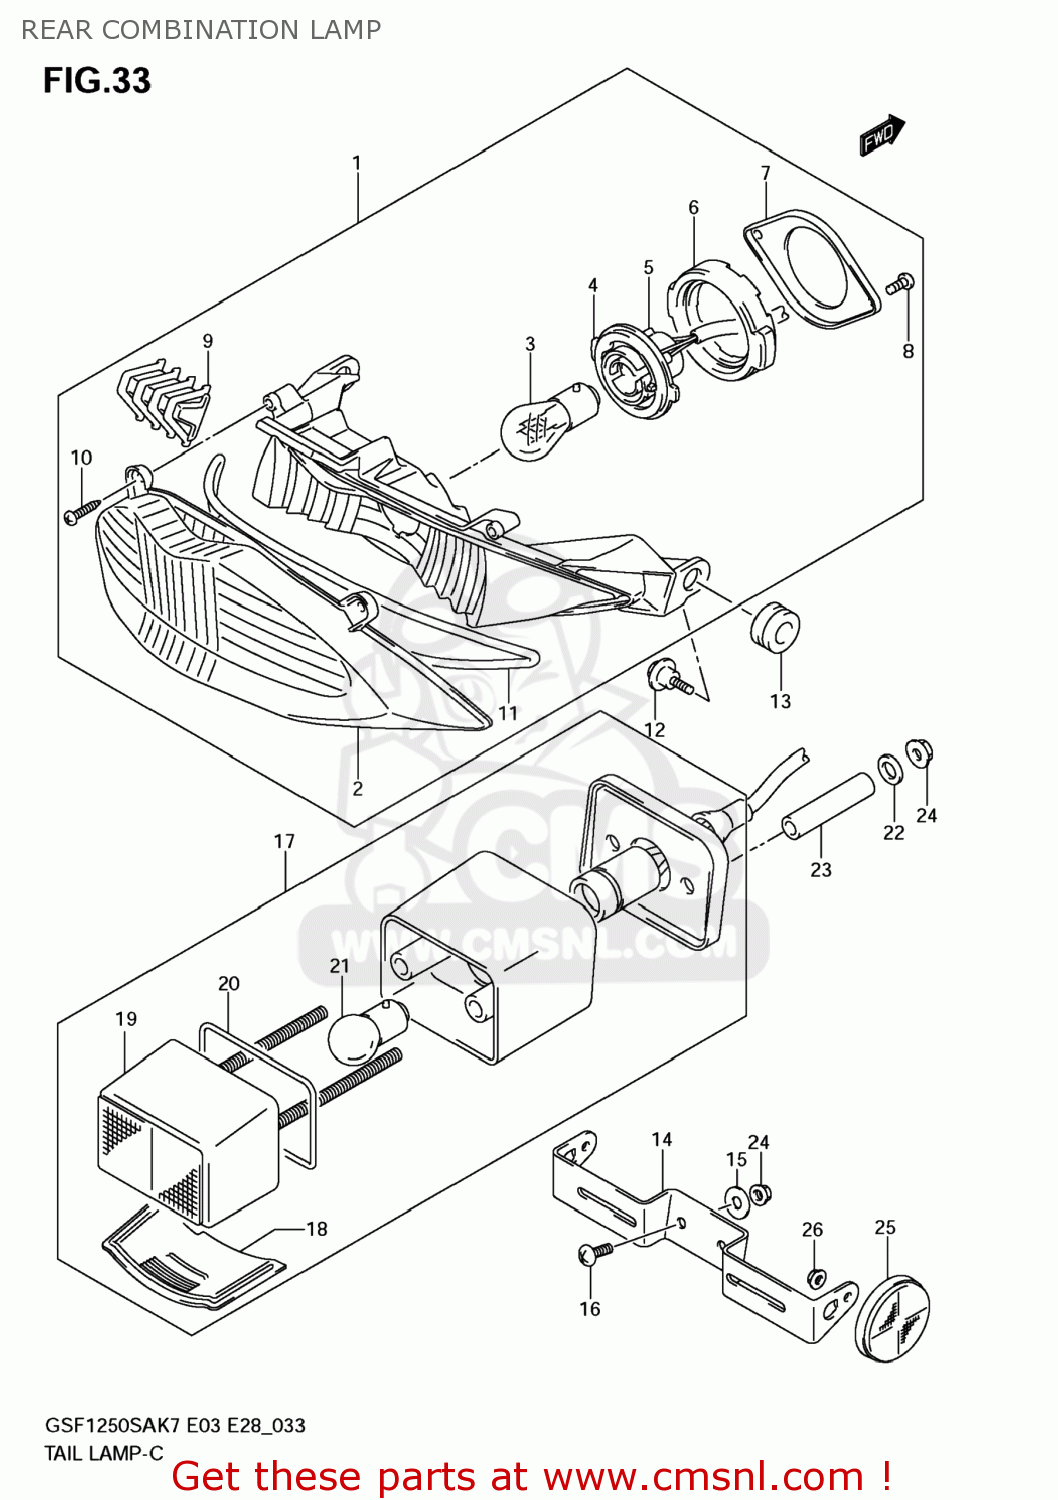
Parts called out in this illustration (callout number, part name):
1	LAMP ASSY,RR COMBINATION
2	LENS
3	BULB(12V21/5W)
4	PLATE NO.1
5	SOCKET & CORD
6	CUSHION
7	PLATE NO.2
8	SCREW
9	CUSHION
10	SCREW
11	GASKET (NAS)
12	SCREW(5X16.2)
13	CUSHION
14	BRACKET,LICENSE PLATE
15	WASHER(6.5X20X1.2)
16	SCREW
17	LAMP ASSY,LICENSE
18	LENS LICENCE
19	COVER,LICENSE LAMP
20	GASKET (NAS)
21	BULB(12V5W,BF150-40160A)
22	WASHER(6.5X20X1.2)
23	SPACER(6.5X9X63.5)
24	NUT
25	REFLECTOR ASSY,RR SIDE
26	NUT
